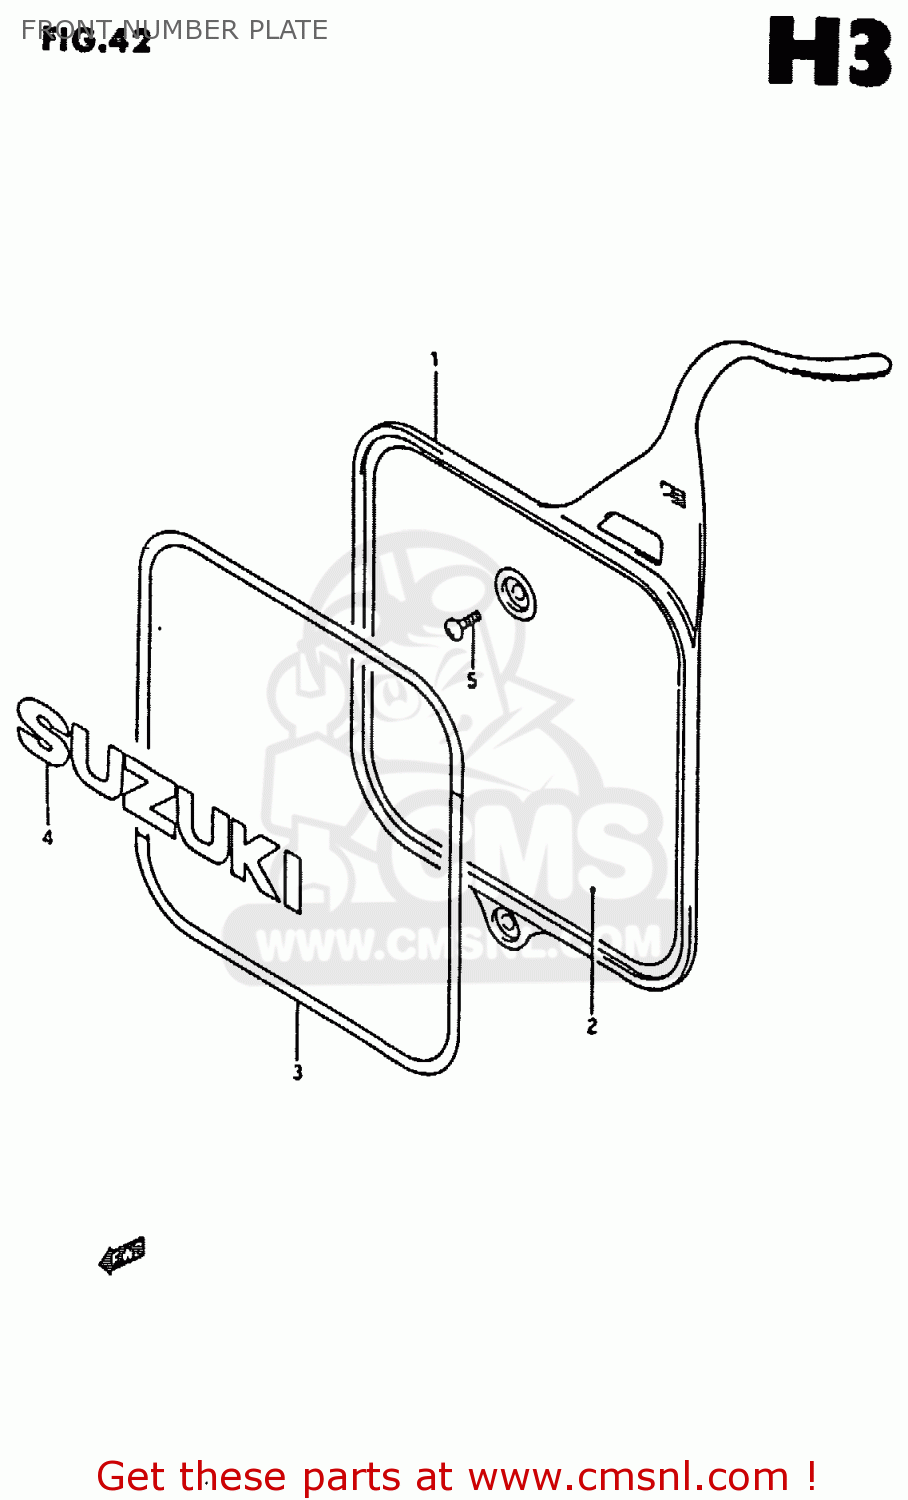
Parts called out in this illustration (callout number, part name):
1	PLATE,NUMBER FR
2	TAPE SET,FRONT NUMBER
3	TAPE SET,FRONT NUMBER
4	EMBLEM, SUZUKI
5	SCREW
